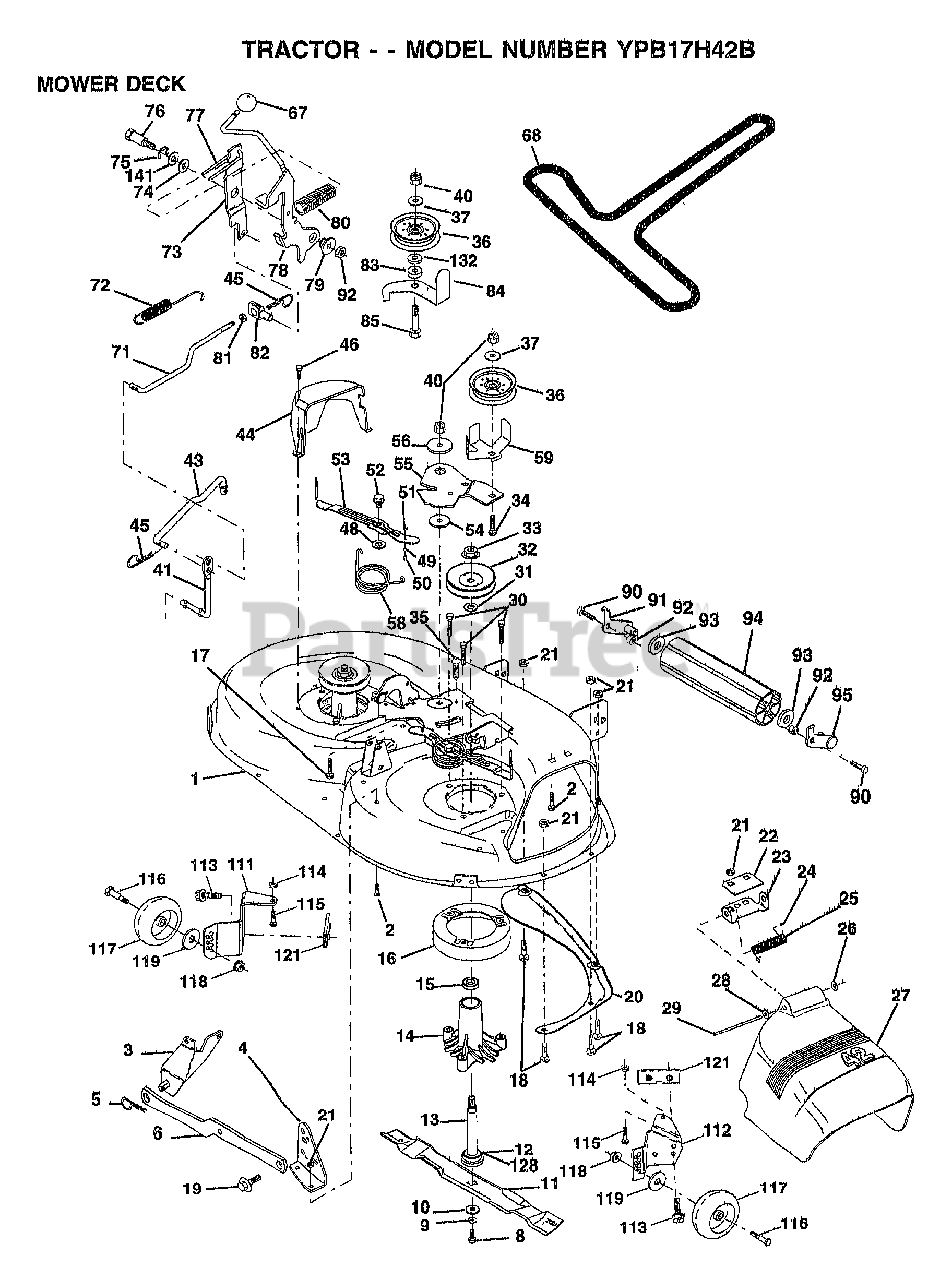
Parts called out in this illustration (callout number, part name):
1	"HOUSING ASSY.42"""
2	BOLT
3	BRKT ASM SWAY BAR
4	BRKT DECK SW BAR
8	BLADE BOLT
10	WASHER.HARD.BLADE
11	"BLADE.42"" HIPERF"
12	BEARING.BALL
14	HSG ASM MANDREL
15	BEARING
16	STRIPPER RND MWR
17	BOLT RDHD 3/8-16
18	BOLT
19	BOLT SHD 5/16-18
20	BAFFLE VORTEX 42
22	STIFFENER BRKT
23	DEFLECTOR BRKT
24	CAP-SLEEVE LT
25	SPRING TORSION
26	NUT PUSH M
27	DEFLECTOR.SHIELD
28	WASHER
29	HINGE ROD
30	"SCREW-THD ROLL,WA"
31	WASHER
32	PULLEY.MANDREL.42
34	BOLT
35	XMAS TREE FASTNER
36	FLAT IDLER PULLEY
37	WASHER
41	PIVOT ROD
43	ROD CLUTCH W/NIBS
44	GUARD MAND LH BLK
45	RETAINER M
46	SCREW.1/4-20X5/8
48	HARD SMALL WASHER
49	ROLLER ASM-CAM
50	SHOULDER BOLT
51	LOCKNUT
52	BOLT.SHLD.5/16-18
53	BRAKE PAD ARM ASM
54	HARDENED WASHER
55	ARM-IDLER
56	SPACER.RETAINER.MOWER
58	SPRING TORSN BRAK
59	GUARD IDLER TUV
67	KNOB.RD.7/16-14
68	BELT.V.T-PATH
71	ROD CLUTCH 38/42
72	RETURN SPRING
73	CLUTCH ARM SECOND
74	WASHER
75	RING
76	SHOULDER BOLT
77	SPRING KEEPER
78	LEVER.ASM.CLUTCH
79	BUSHING
80	SPRING.CLUTCH.MWR
81	NUT
82	TRUNION ADJ
83	WASHER
84	"KEEPER-BELT,FIXED"
85	BOLT
90	BOLT
92	NUT
93	WASHER
111	BRACKET.GWHL.LH.
112	BRACKET.GWHL.RH.
113	SCREW
116	BOLT M
117	WHEEL.GUAGE
118	LOCKNUT
119	WASHER
121	BRACKET.EXTRD.GWL
128	WASHER.FELT.
132	WASHER GT
141	WASHER .T
